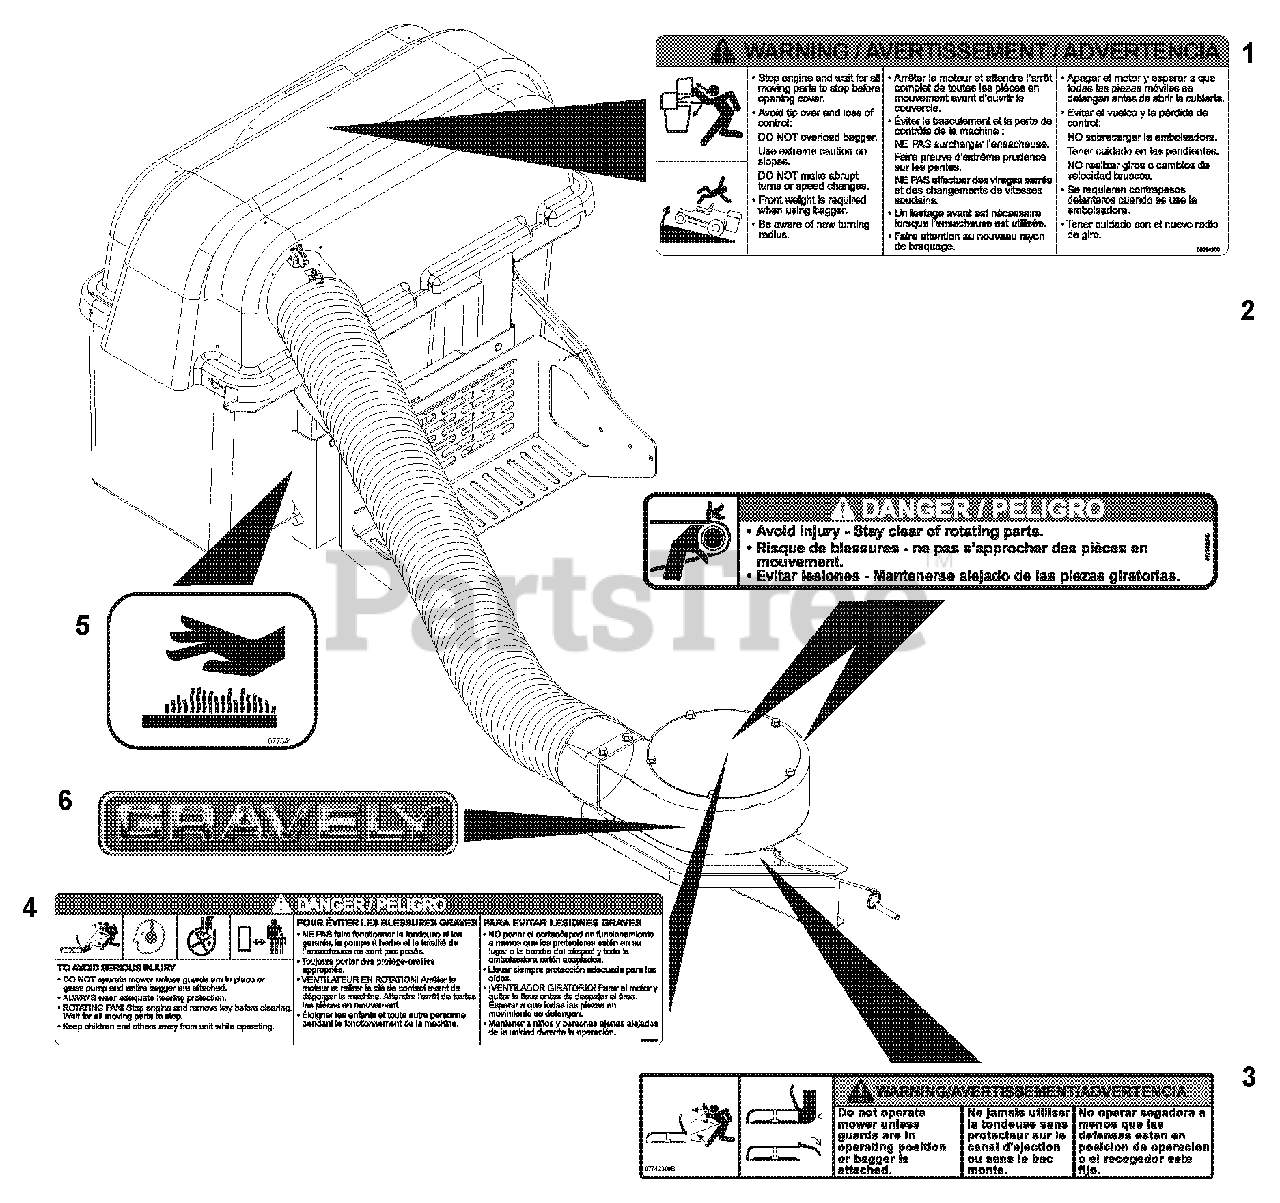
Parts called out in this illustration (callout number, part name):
1	Decal-Warning, Bagger Cover
2	Decal, Danger
3	Decal, Warning
4	Decal, Danger, Grass Pump
5	Decal, Hot Surface
6	Decal, Gravely
